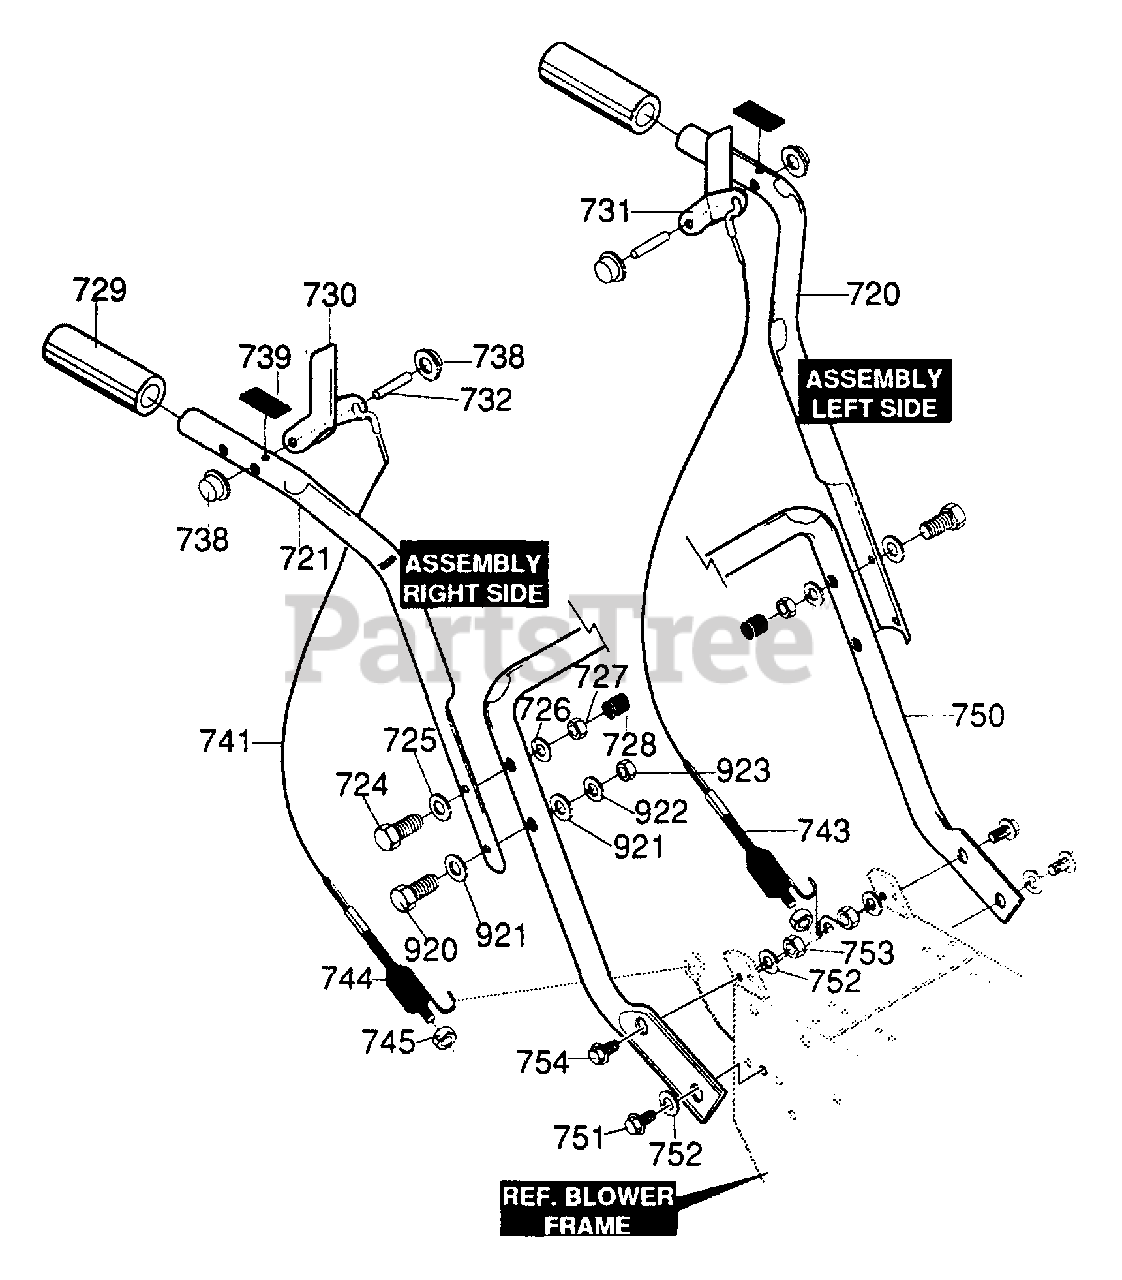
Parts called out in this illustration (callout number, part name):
720	HANDLE, UPPER, LH
721	HANDLE, UPPER, RH
724	SCREW, 3/8-16 x 3.00 HHCFT
725	FLATWASHER, .406 x .81 x.065
726	WASHER, REGSPTLK .393 x .68 x .10
727	NUT, 3/8-16 REGHXCTRLK
728	STOP, PLASTIC .375
729	GRIP, HANDLE 1.25 x 4.38
730	HANDLE, RH ASSEMBLY
731	HANDLE, LH ASSEMBLY
732	PIN, PIVOT .31 OD
738	NUT, PUSH ON CAP .312 OD
739	BUMPER, RECT W/FLAT TOP
741	CABLE, CLUTCH 32.19" TRACTION
743	SPRING TENSION
744	SPRING, AUGER CLUTCH
745	NUT, 1/4-20 REGHEXCTRLK
750	HANDLE, LOWER
751	SCREW, 5/16-18 x .75 HHC
752	WASHER, HVSPTLK .328 x .60 x .09
753	NUT, 5/16-18 REGHEX
754	SCREW, 5/16-18 x .75 WAHHTAP
920	SCREW, 3/8-16 x 2.00 HHC
921	FLATWASHER, .406 x .81 x .065
922	WASHER, REGSPTLK .393 x .68 x .10
923	NUT, 3/8-16 REGHEXCTRLK
